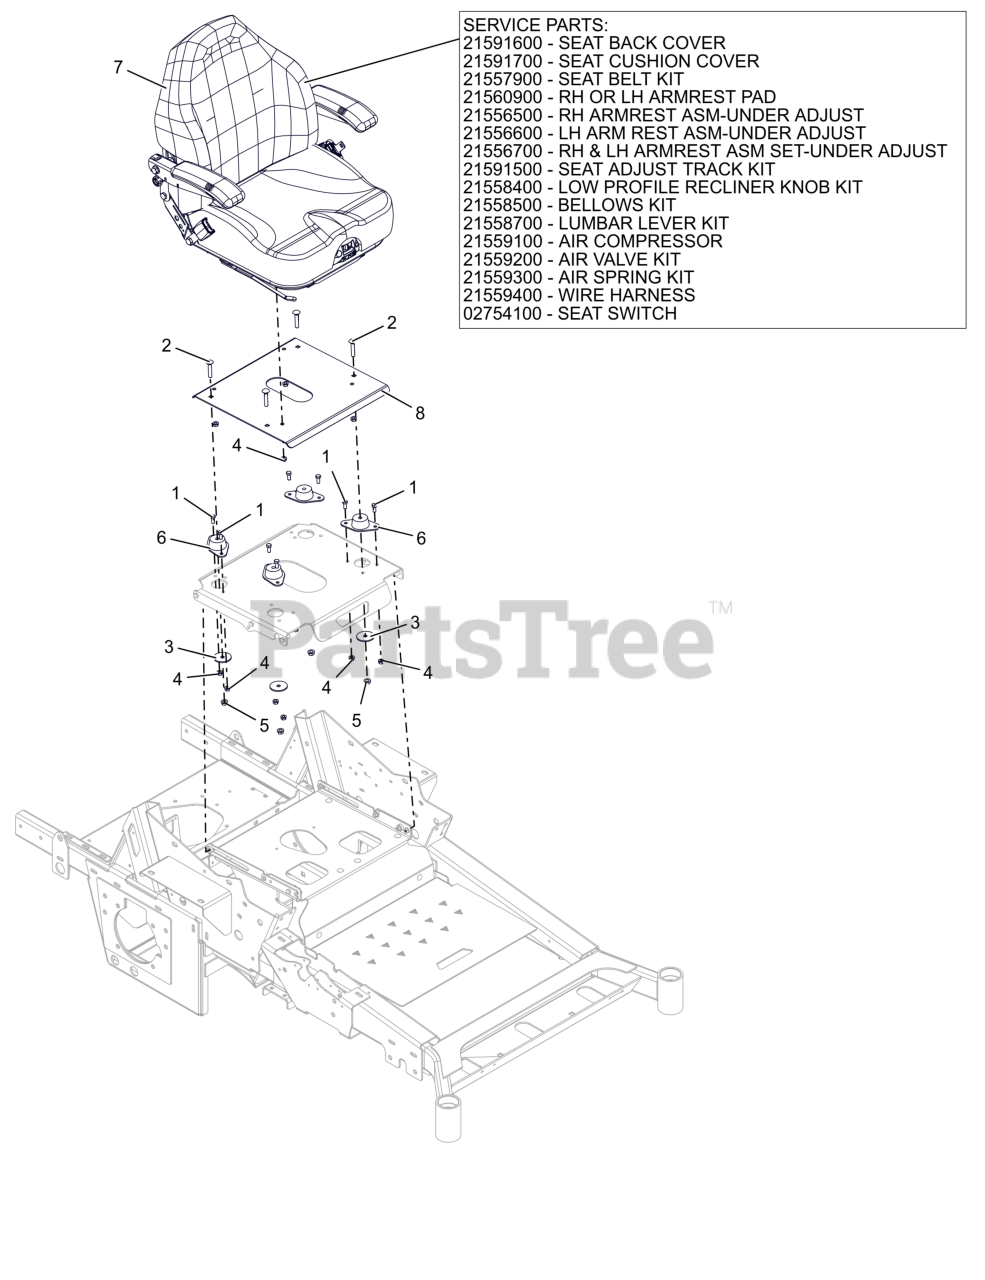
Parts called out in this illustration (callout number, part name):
1	BLT,HEX .31-18X.75 G5 ZCC
2	BLT, RHSN .38-16X2.00 G5 ZCC
3	WSHR-FL-STL 0.406X2X0.125 ZCC
4	NUT,LK-CTR-FLG .31-18 GF ZCC
5	NUT-LK-CTR-FLG .375-16 GF ZCC
6	MOUNT, FAIL-SAFE COMPRESSION
7	SEAT- AIR SUSPENSION
7	SEAT BACK COVER
7	SEAT CUSHION COVER
7	KIT, SEAT BELT
7	PAD, ARMREST RH OR LH (HARD)
7	ARMREST, RH ASSEMBLY
7	ARMREST, LH ASSEMBLY
7	SET, RH & LH ARMREST ASSEMBLY
7	SETA ADJUST TRACK KIT
7	KIT, LOW PROFILE RECLINER KNOB
7	KIT, BELLOWS
7	KIT, LUMBAR LEVER
7	COMPRESSOR, AIR RIDE SEAT
7	KIT, AIR VALVE AND LINE
7	KIT, AIR SPRING
7	HARNESS, SEAT WIRE
7	SWITCH- SNAP MTG N.O.
8	PLATE- SEAT MOUNTING
